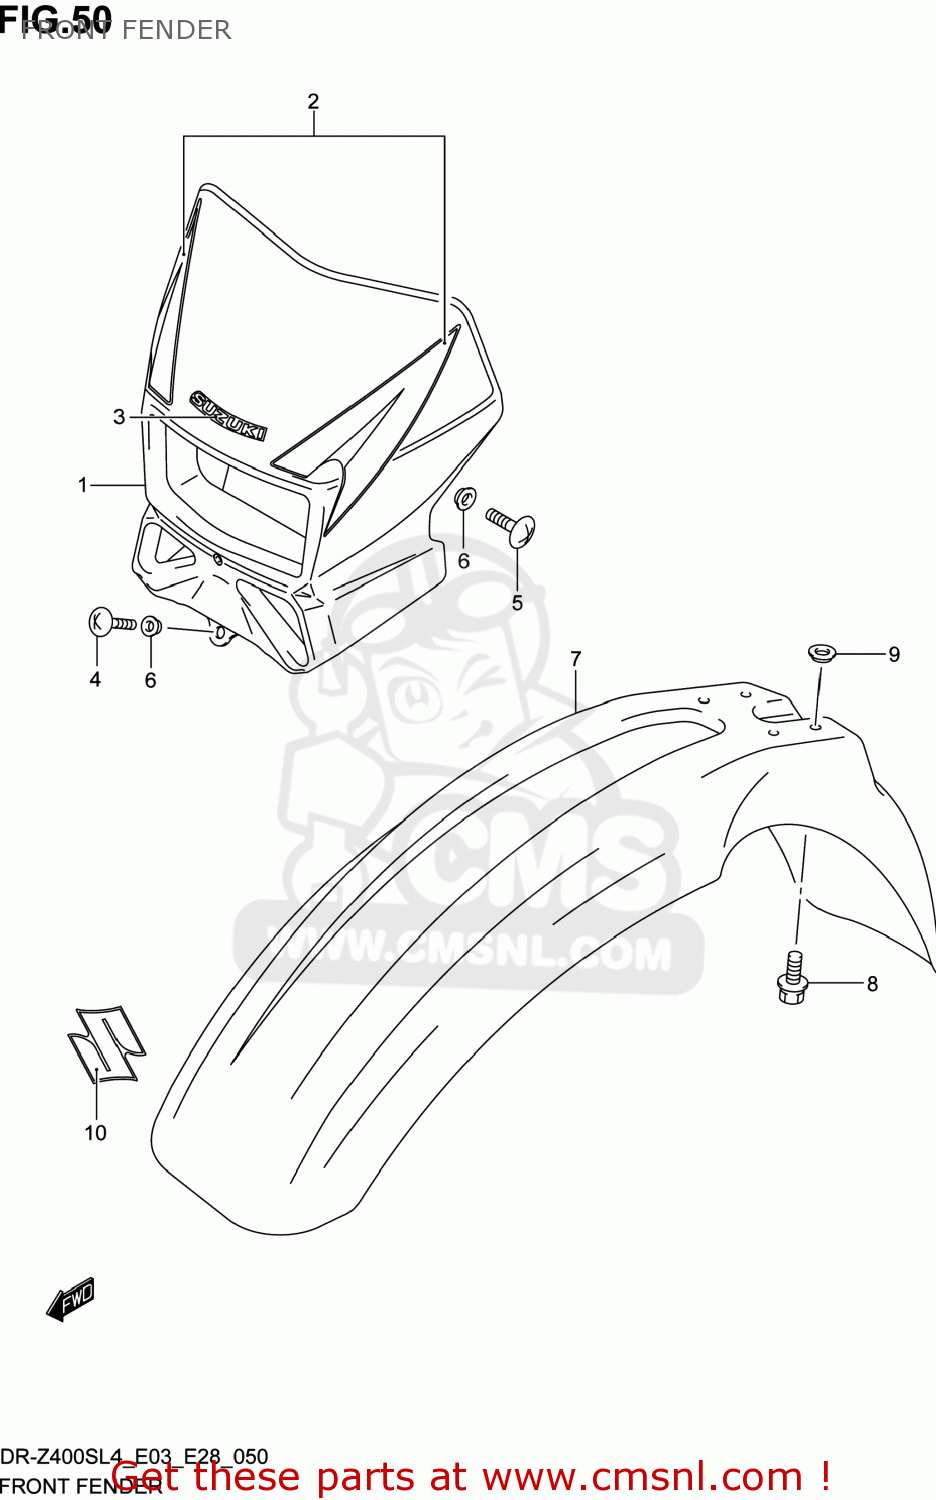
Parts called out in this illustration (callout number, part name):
1	COVER,HEADLAMP
2	TAPE SET,HEADLAMP HOUSING
3	EMBLEM,SUZUKI
4	SCREW
5	SCREW
6	WASHER
7	FENDER,FR
8	BOLT(6X16)
9	WASHER
10	EMBLEM,S
